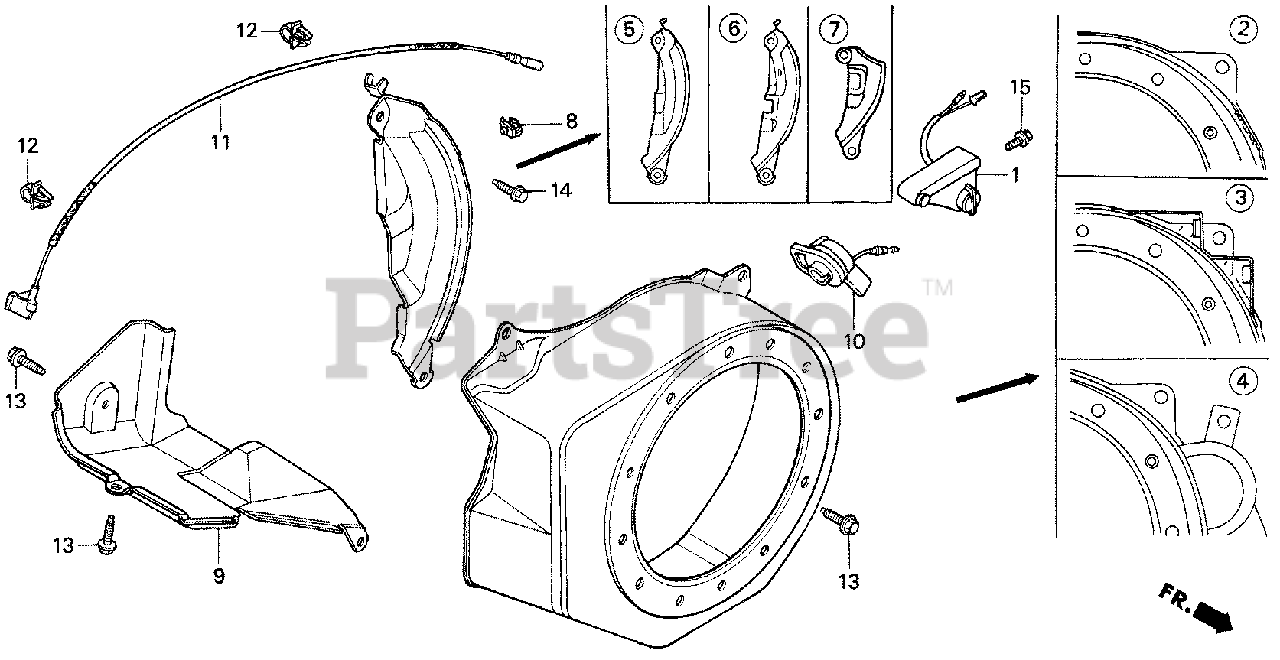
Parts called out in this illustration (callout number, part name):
2	COVER, FAN *R8* (BRIGHT RED)
2	COVER, FAN *R280* (POWER RED)
5	PLATE, SIDE
5	PLATE, SIDE (STD)
9	SHROUD
10	SWITCH ASSY., ENGINE STOP
11	WIRE, STOP SWITCH
11	WIRE, STOP SWITCH (370MM)
12	HOLDER, STOP SWITCH WIRE
13	BOLT, FLANGE (6X12) (CT200)
14	BOLT, FLANGE (6X20) (CT200)
